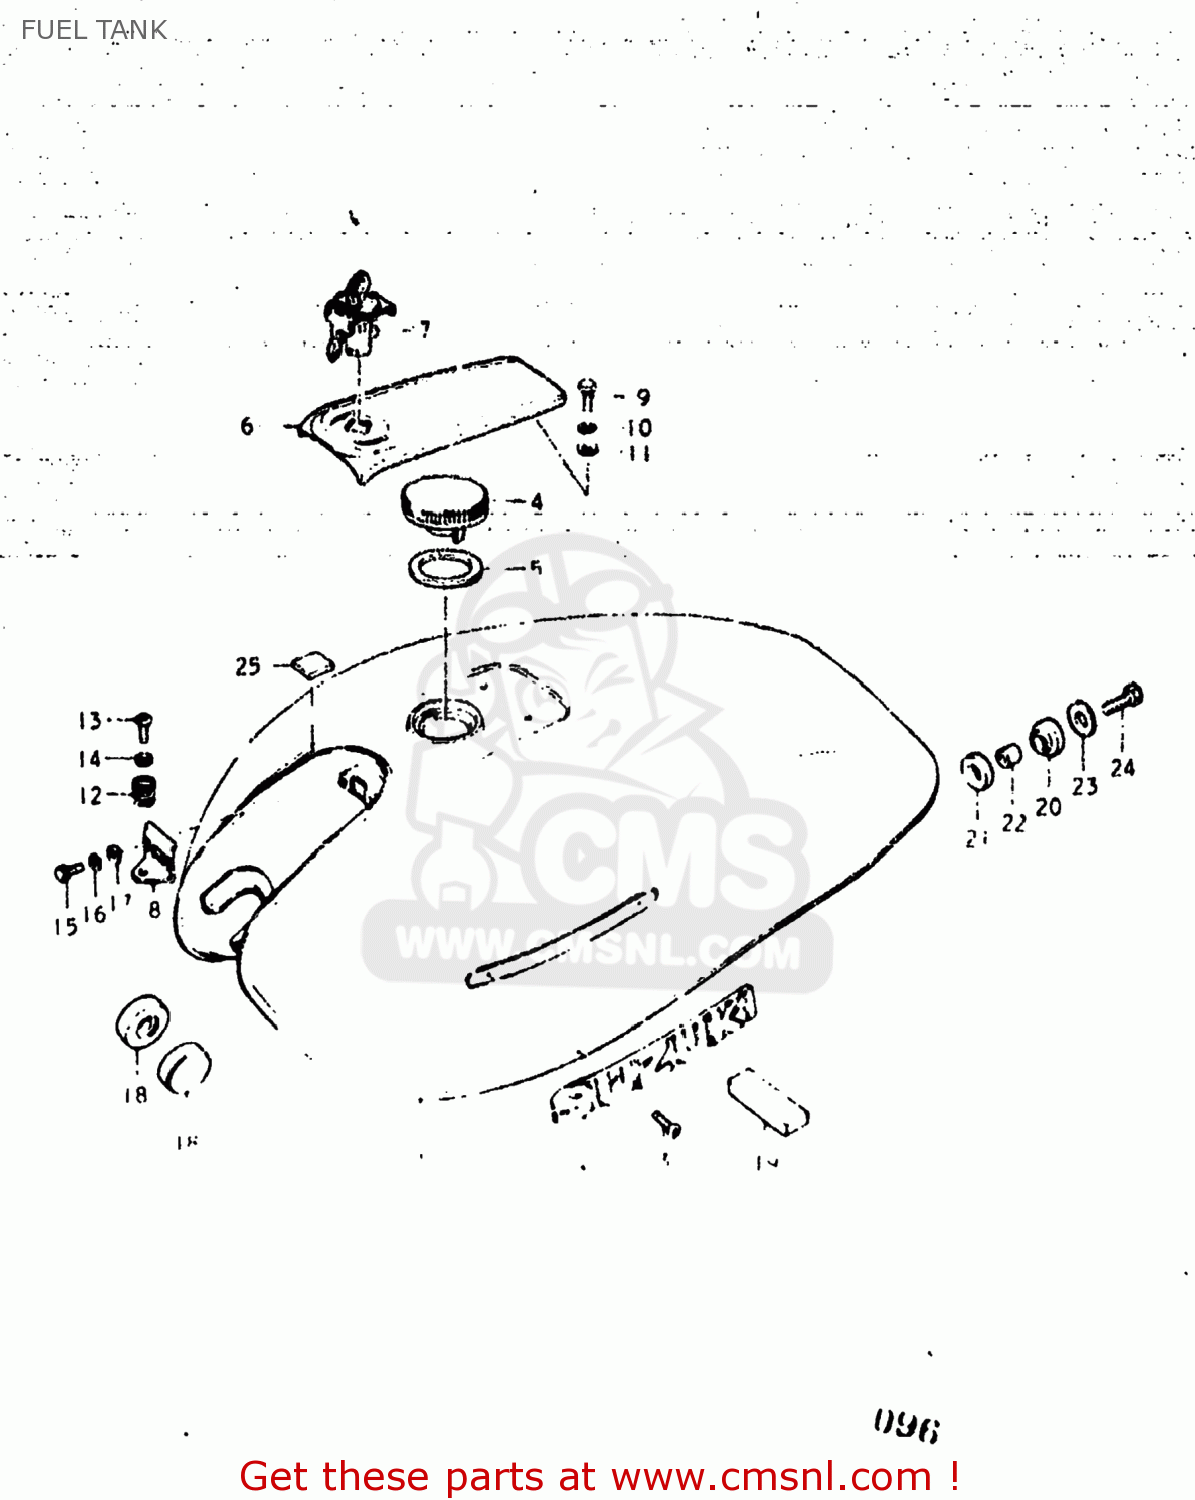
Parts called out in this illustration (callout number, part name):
1	TANK ASSEMBLY,FUEL
2	EMBLEM,FUEL TANK
3	SCREW
4	CAP,FUEL TANK
5	GASKET (NAS)
6	COVER,FUEL TANK
7	LOCK,FUEL TANK FR COVER
8	HOLDER,FUEL TANK FRONT COVER
9	BOLT
10	LOCK WASHER
11	WASHER
12	SPRING
13	SCREW
14	LOCK WASHER
15	BOLT
16	LOCK WASHER
17	WASHER 5MM
18	CUSHION
19	CUSHION
20	CUSHION
21	CUSHION
22	SPACER(8.5X12X19)
23	WASHER (8.5X29X1.6)
24	BOLT
25	CUSHION,FUEL TANK FR COVER
